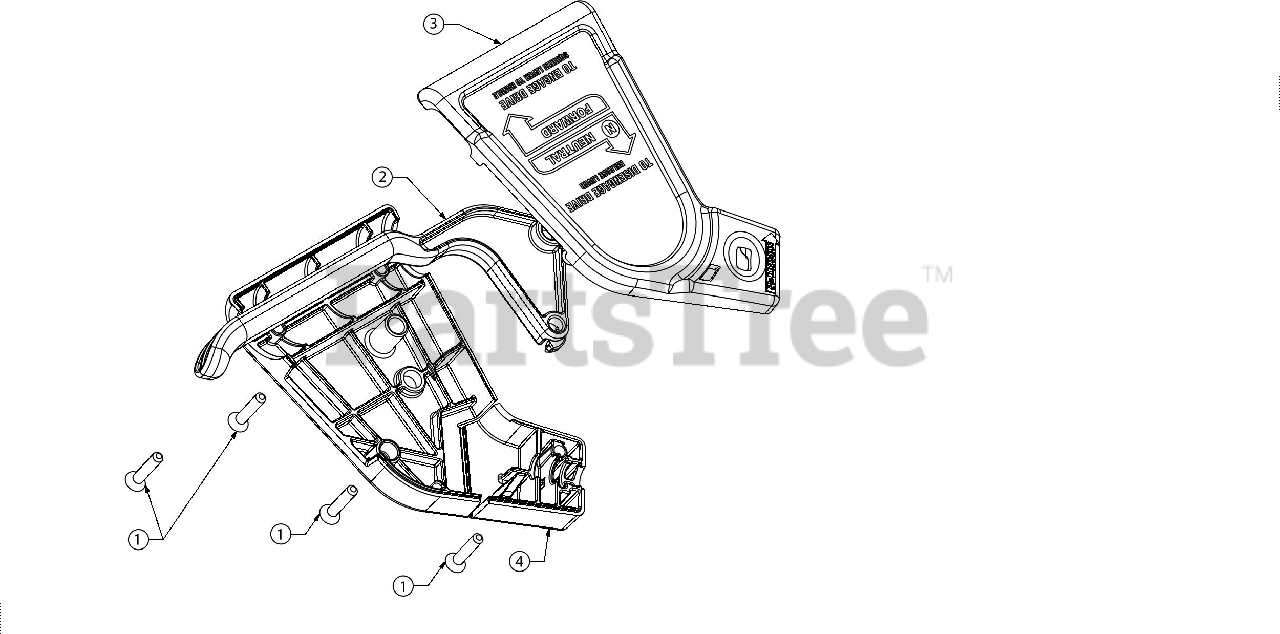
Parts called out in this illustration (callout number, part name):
1	SCREW #10-16 X 1.00
2	ENGAGEMENT LEVER
4	SQUEEZEBOX CONTROL COVER
